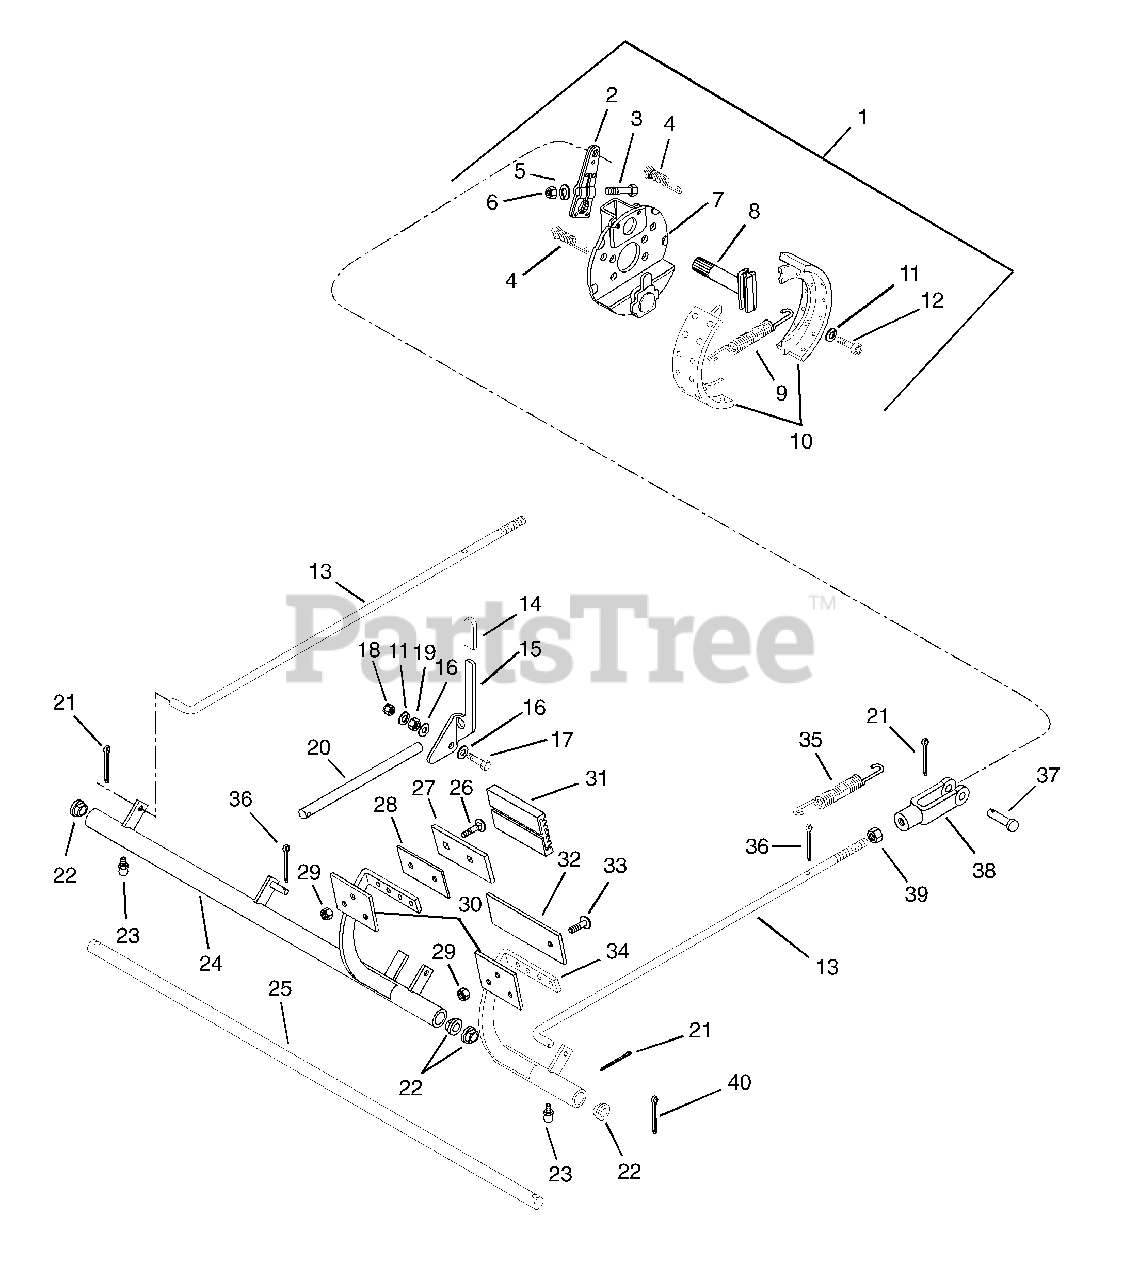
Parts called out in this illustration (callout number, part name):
1	Brake, 7 x 1.75 Mechanical
2	Arm, Cam Lever
3	Bolt-Hex .31-24 x 1.75
4	Spring, Shoe Ret Box
5	Washer-Lock .313 x .078
6	Nut-Hex .312-24 Grade 2
7	Plate, Brake
8	Cam, Brake
9	Spring, Shoe Return
10	Kit, Brake Shoe
11	Washer-Lock .38 x .094
12	Screw-Cap .38-16 x 1.25
13	Rod, Brake
14	Tip-Brake Lock Lever
15	Arm, Parking Brake Lock
16	Washer-Flat-Nylon .375 x .75 x .060
17	Bolt-Hex .38-16 x 1.25 Grade 5
18	Nut-Locking-Center .38-16
19	Nut-Hex .38-16
20	Rod, Brake Lock
21	Pin-Cotter .09 x .75
22	Bushing-Flange .630 x 1.000 x .625
23	Fitting-Lube .25-28 x .256
24	Weldment, Brake Pedal
25	Shaft, Brake
26	Bolt-Round Head Square Neck .25-20 x 1.25 Grade 5
27	Pedal, Brake
28	Plate, Brake
29	Nut-Locking-Center .25-20
30	Plate, Brake Lock Backing
31	Pad, Pedal
32	Arm, Brake Lock
33	Screw-Machine .25-20 x 1.00
34	Weldment, Brake Pedal
35	Spring-Tension .091 x .500 x 5.50
36	Pin-Cotter .12 x .75
37	Pin-Clevis .375 x .948
38	Clevis, .38-24 Adjustable
39	Nut-Jam .375-24
40	Pin-Cotter .12 x 1.25
